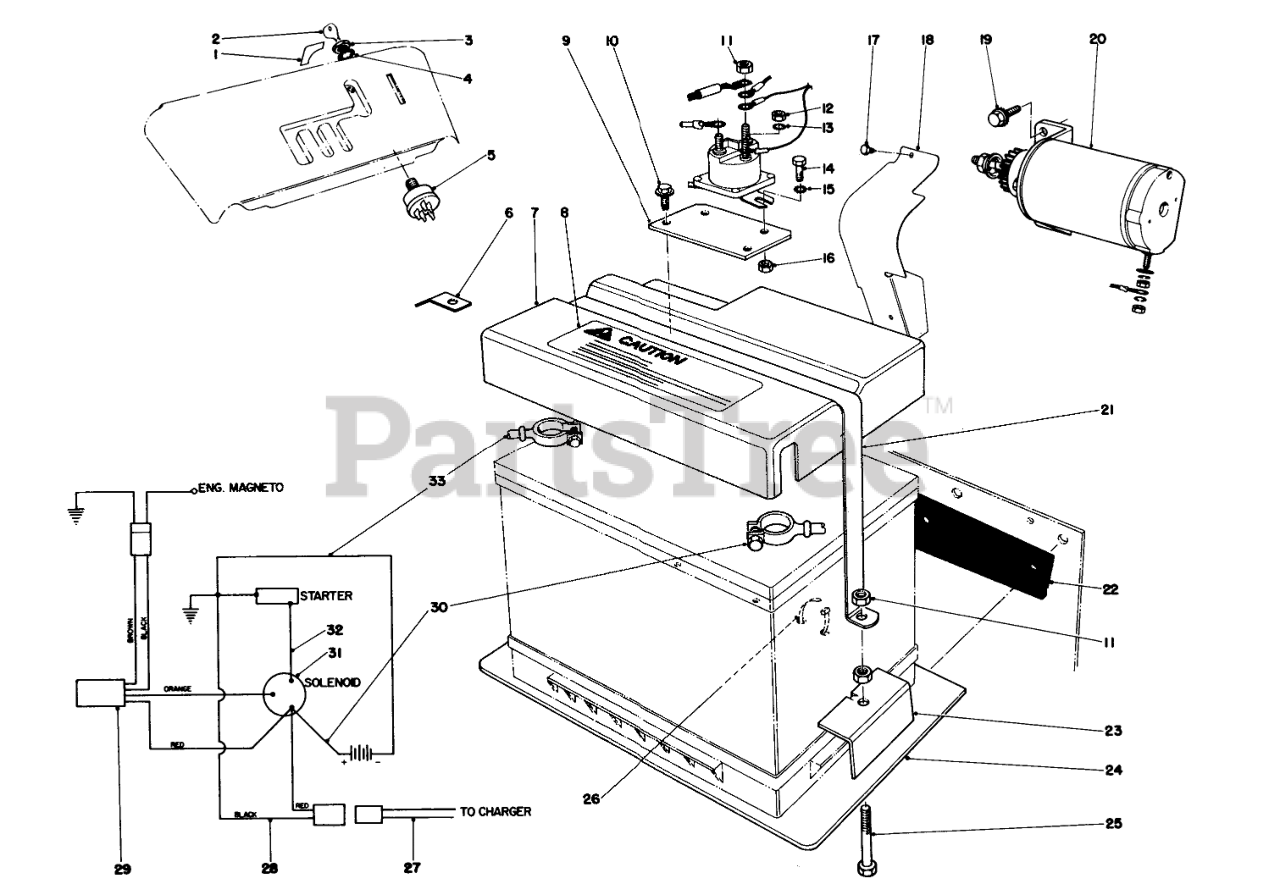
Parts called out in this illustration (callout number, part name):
1	Decal Key Switch
2	Key
3	NUT-HH
4	WASHER-TOOTH, INTERNAL
5	SWITCH-STARTER
6	Bracken Wire Clamp
7	Battery Cover (Incl. Ref. #8)
8	Decal
9	Bracket Solenoid
10	SCREW-HWH
11	NUT-HEX
12	NUT-HEX
13	WASHER-LOCK, INT
14	SCREW-HH
15	WASHER-LOCK/EXT
16	NUT-LOCK, NI
17	Hex Hd. Sems Screw
18	Pinion Shield
19	Screw-HH
20	Starter Motor & Pinion Assy.
21	Strap Battery
22	Batery Isolation Pad
23	BATTERY CLAMP
24	Battery Mounting Plate
25	SCREW-HH
26	TIE-CABLE
27	MALE WIRE ASM
28	FEMALE WIRE ASM
29	12 V IGN WIRE HARNESS
30	BATT-SOLENOID CABLE
31	SOLENOID
32	STRT MTR-SOLNOID WIRE
33	BATT-GROUND CABLE
